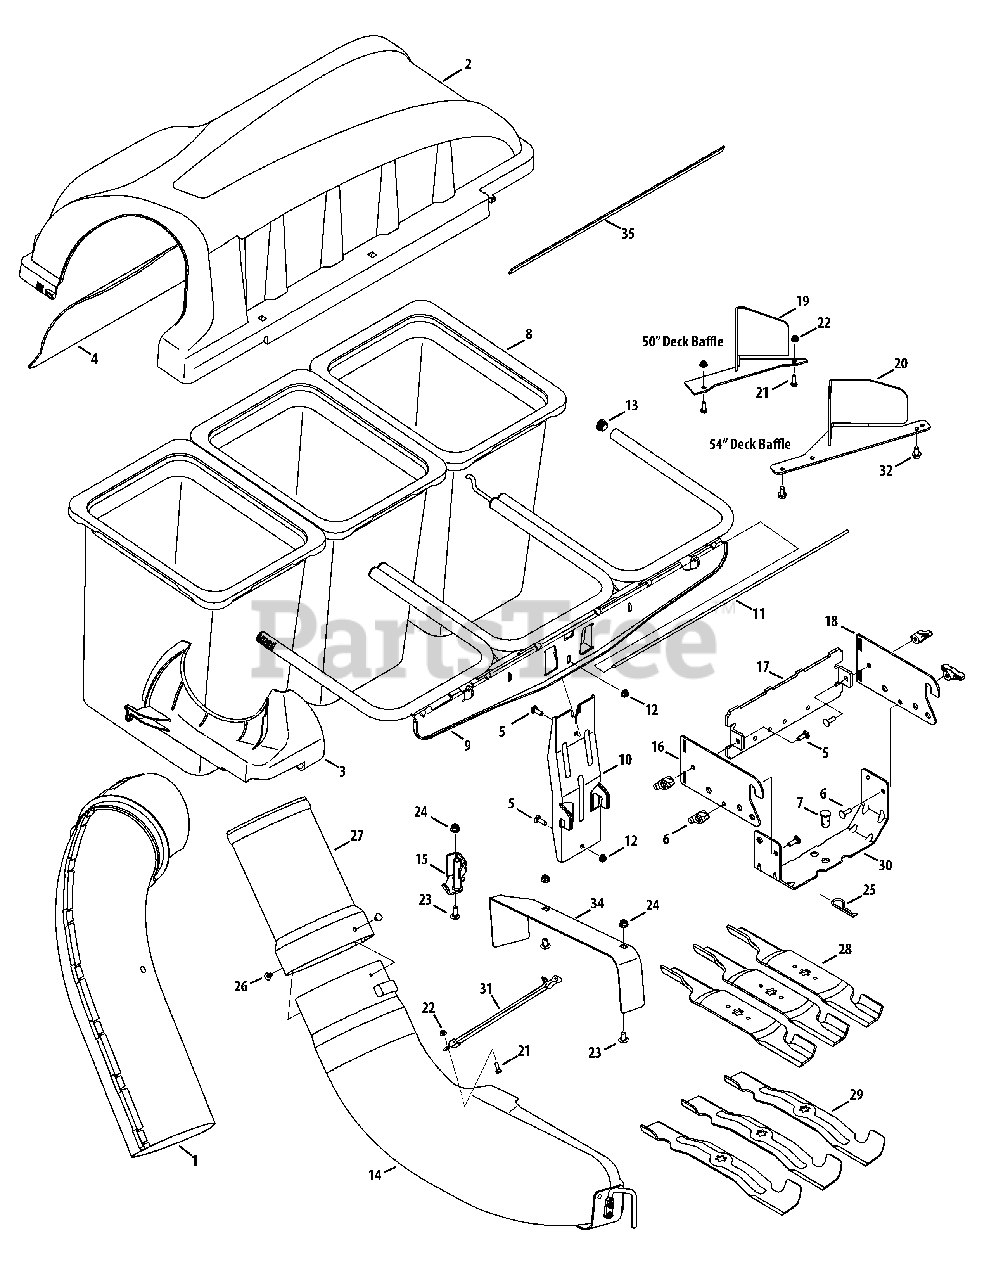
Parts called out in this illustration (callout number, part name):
1	Upper Chute Assembly
2	Triple Bagger Cover Assembly
3	Upper Chute Support
4	Bagger Cover Screen
5	Carriage Screw, 5/16-18 x 1.00"
6	Wing Knob, 5/16-18
7	Clevis Pin, .62" Dia.
8	Grass-bag Assembly
9	Triple Bag Support Assembly
10	Vertical Support Bracket
11	Cover Hinge Pin
12	Flange Lock Nut, 5/16-18
13	End Plug
14	Discharge Chute Elbow, (50/54" Deck)
15	Chute Stop-Bracket
16	Hitch Bracket, RH
17	Universal Rear Attachment Bracket
18	Hitch Bracket, LH
19	Deck Baffle, 50"
20	Deck Baffle, 54"
21	Tap Screw, 1/4 - 20 x .750 (50" Deck)
22	Flange Lock Nut, 1/4 - 20 (50" Deck)
23	Carriage Screw, 3/8 - 16 x 1.00"
24	Flange Lock Nut, 3/8 - 16
25	Internal Cotter Pin, .148 x 3.00
26	Ratchet Clip, .250
27	Bagger Chute Adapter, 7 In.
28	Blade, 18.50 Lg., High Lift
29	Blade, 17.90 Lg., Star Bagging
30	Hitch Support Bracket
31	Chute Strap
32	Tap Screw, 5/16-18 x .750 (54" Deck)
34	Discharge Chute Plate
35	Adhesive Foam Strip
